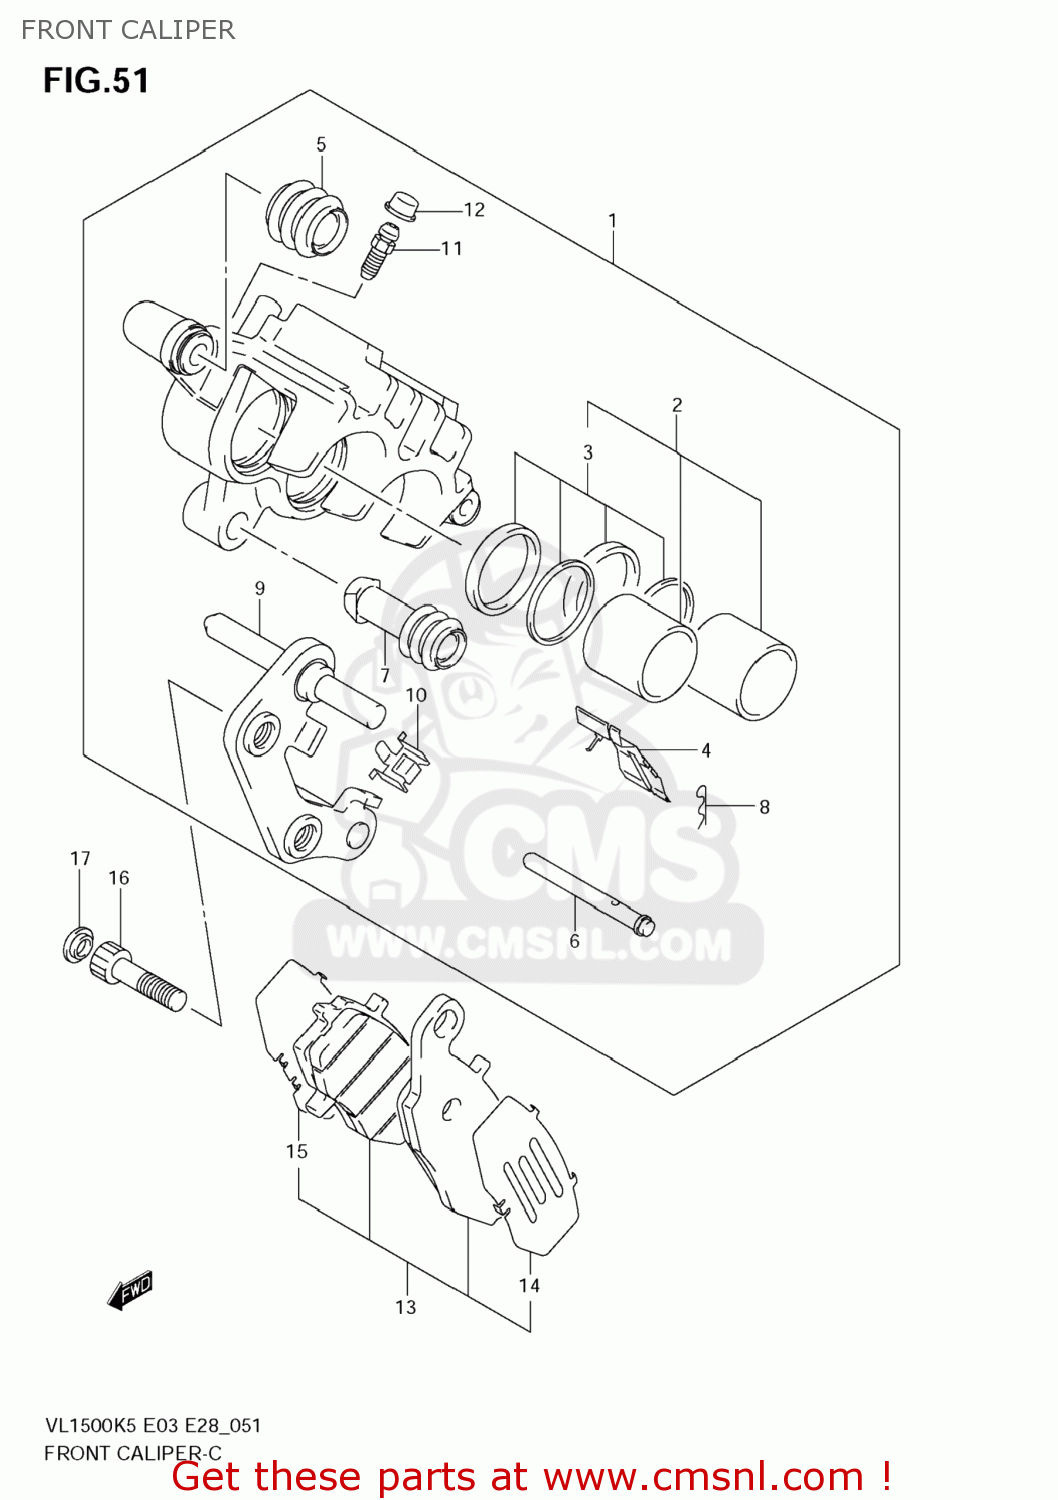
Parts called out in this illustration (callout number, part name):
1	CALIPER ASSY,FR,R
2	PISTON SET
3	SEAL SET,PISTON
4	SPRING,PAD,R
5	BOOT,AXLE
6	PIN,PAD
7	INSULATOR,AXLE
8	CLIP,PAD PIN
9	CARRIER,CALIPER,R
10	GUIDE,PAD
11	BLEEDER
12	CAP,BLEEDER PLUG
13	PAD & SHIM SET (NAS)
14	SHIM,PAD
15	SHIM,PAD NO.2
16	BOLT(10X33)
17	CAP(OD:12)
